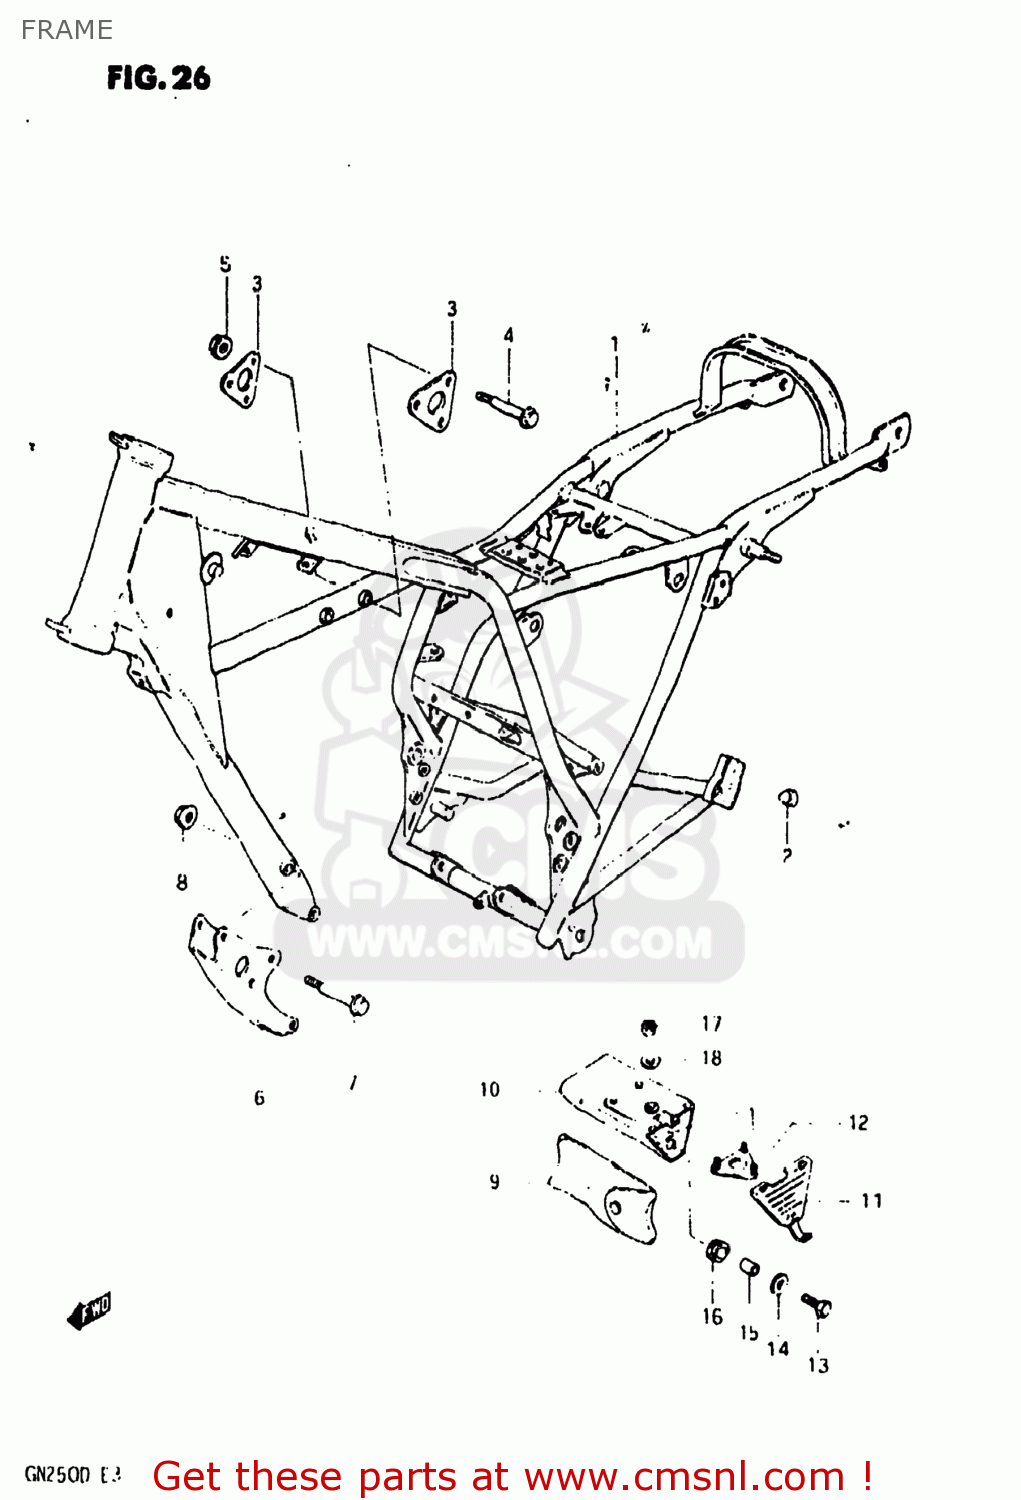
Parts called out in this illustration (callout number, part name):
1	FRAME
2	CAP
3	PLATE,ENGINE MOUNT UPR
4	BOLT
5	NUT
6	PLATE,ENGINE MOUNTING
7	BOLT 8X65
8	NUT
9	TOOL SET
10	BOX,TOOL
11	CAP,TOOL BOX
12	PLATE,TOOL HOLDER
13	BOLT, UPPER
14	WASHER (6.5X20X1.2)
15	SPACER (6.8X10X10)
16	CUSHION
17	NUT
18	WASHER
